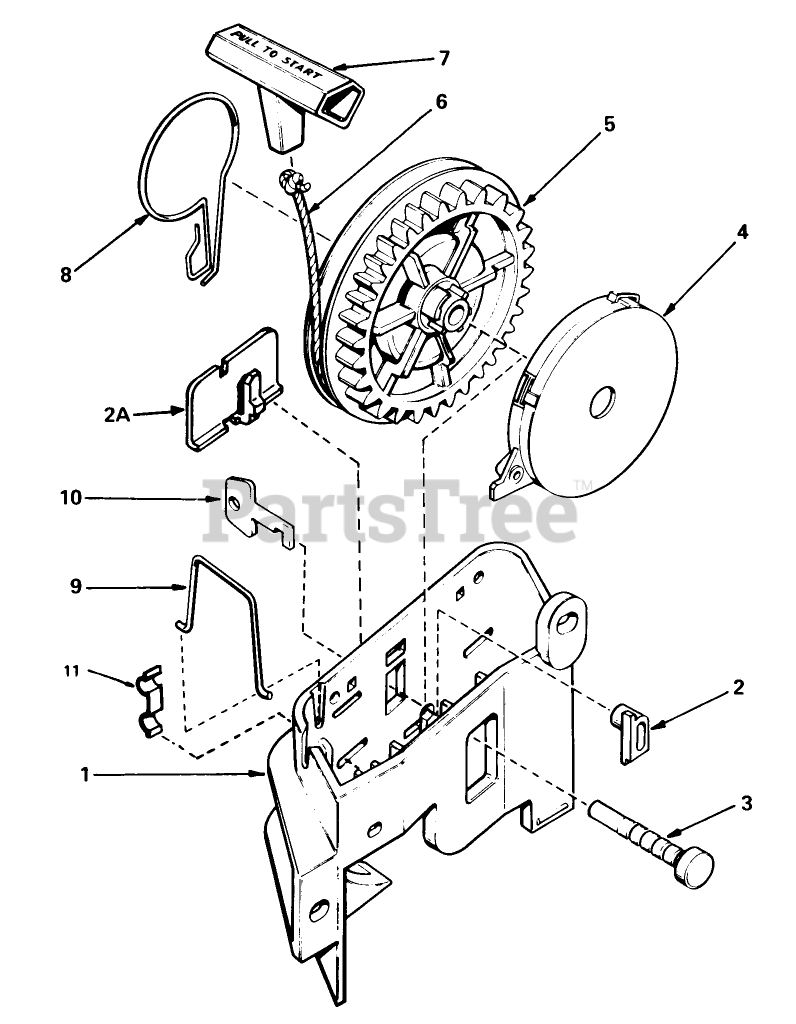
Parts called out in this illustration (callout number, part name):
1	Bracket Starter
2	Pawl, Locking Not used on all engine models)
2A	Clip, Starter Bracket (Used On Starters Not Equipped With Pawl, Ref. No. 2)
3	Pin-Pulley
4	Spring Assy., Rewind (Incl. Ref. #3)
5	Pulley
6	Rope-Starter (98 cut to length)
7	Handle-Starter
8	Brake
9	Clip-Rope
10	Key (Not Used On All Engine Models
11	Clip-Bowden Wire (Not used on all engine models)
